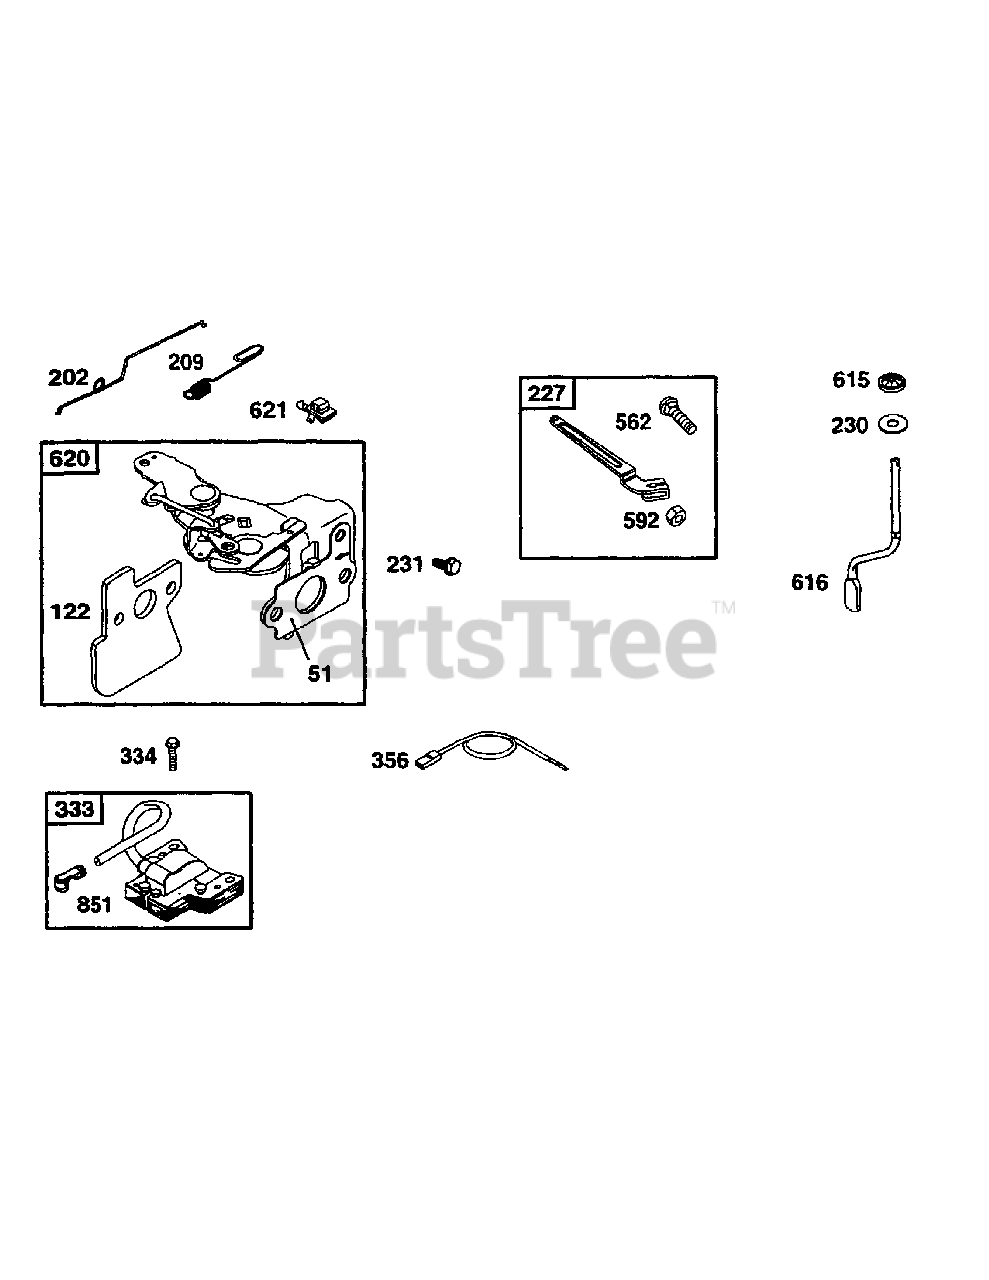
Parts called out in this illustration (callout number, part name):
51	Intake Gasket
122	Carburetor Spacer
202	Mechanical Gov. Link
209	Gov. Spring
227	Gov. Lever
230	Flat Washer
231	Screw Hex
333	Magneto
334	Screw Hex
356	Stop Wire
562	Gov. Lever Bolt
592	Hex Nut
615	Gov. Retainer
616	Gov. Crank
620	Control Bracket
621	Stop Switch
851	Cable Terminal
